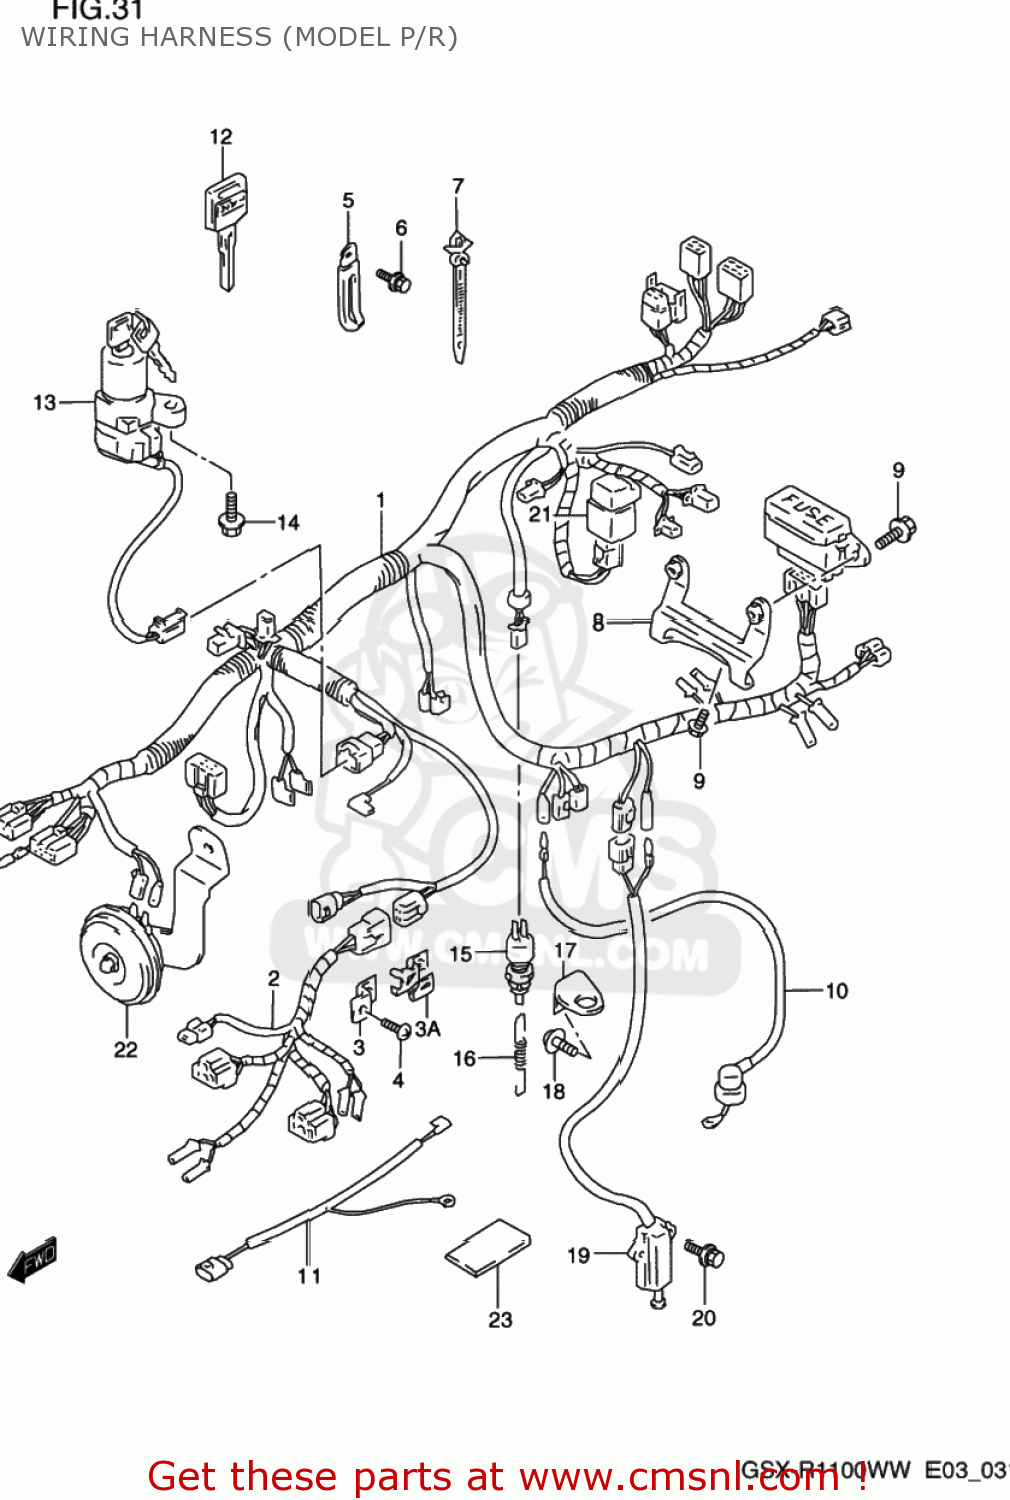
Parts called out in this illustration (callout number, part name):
1	HARNESS,WIRING
2	HARNESS,WIRING NO.2
3	HOLDER,COUPLER
3A	HOLDER,COUPLER
4	SCREW
5	CLAMP
6	BOLT
7	CLAMP(L:90)
8	BRACKET,FUSE BOX
9	BOLT
10	WIRE,OIL PRESSURE SWITCH LEAD
11	WIRE,WATER TEMPERATURE GAUGE
12	KEY,BLANK
13	LOCK ASSEMBLY,STEERING
14	SCREW(6X18)
15	SWITCH ASSY,STOP LAMP
16	SPRING
17	BRACKET,STOP LAMP SWITCH
18	SCREW(6X12)
19	SWITCH ASSY,SIDE STAND WARNING
20	BOLT
21	RELAY ASSY
22	HORN ASSEMBLY,LOW PITCH
23	TAPE
